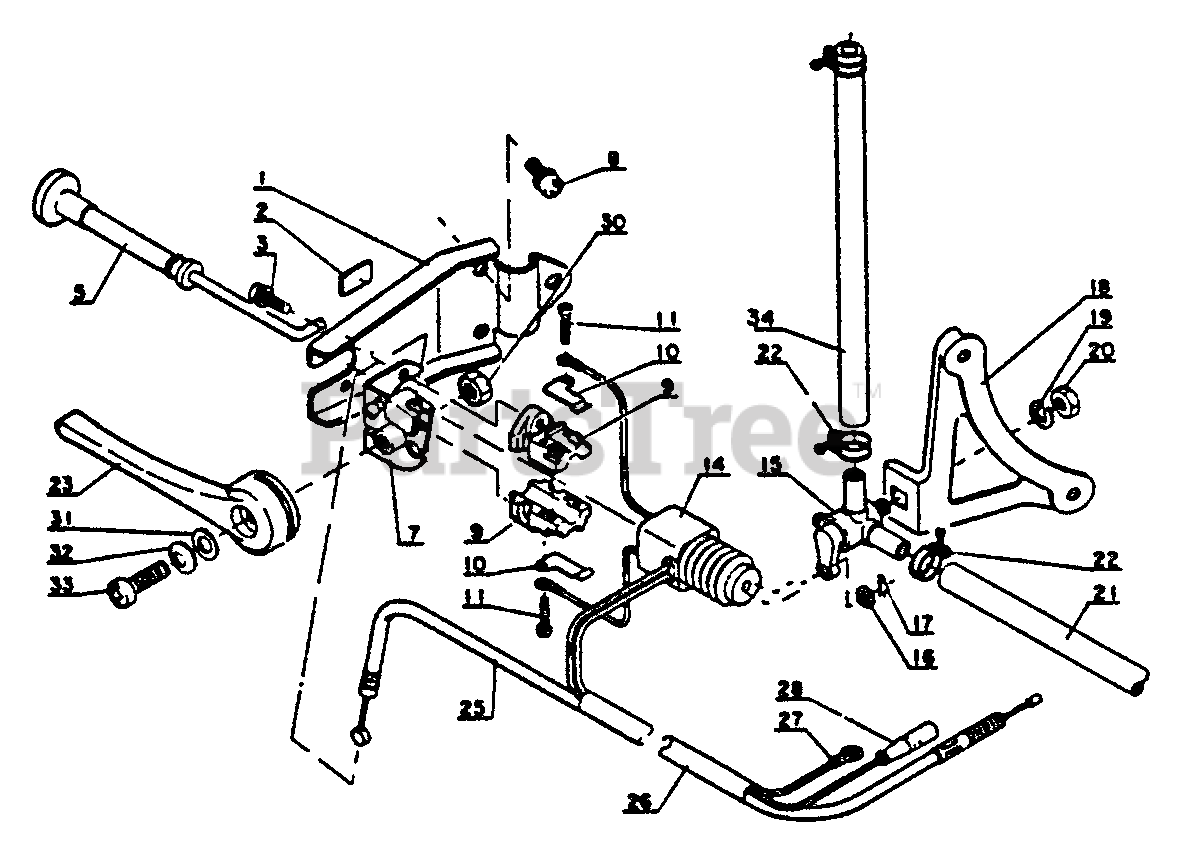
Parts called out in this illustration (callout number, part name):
1	BRACKET, SWITCH
2	LABEL - STOP
3	SCREW - 4X12
5	KNOB
7	BRACKET, THROTTLE LEVER
8	SCREW - 5X10
9	BODY, SWITCH
10	CONTACT, SWITCH
11	SCREW - 3X15
14	BRACKET, SWITCH
15	FUEL VALVE ASSY
16	WASHER - 4
18	BRACKET, FUEL VALVE
19	LOCKWASHER - 6
21	PIPE - FUEL
22	RETAINER, PIPE
23	TRIGGER, THROTTLE
25	THROTTLE CONTROL ASSY
26	CABLE, THROTTLE
27	LEAD - GROUND
28	LEAD - IGNITION
30	LOCKNUT - 6
31	WASHER - 6
32	WASHER
33	SCREW - 6X20
34	PIPE - FUEL
